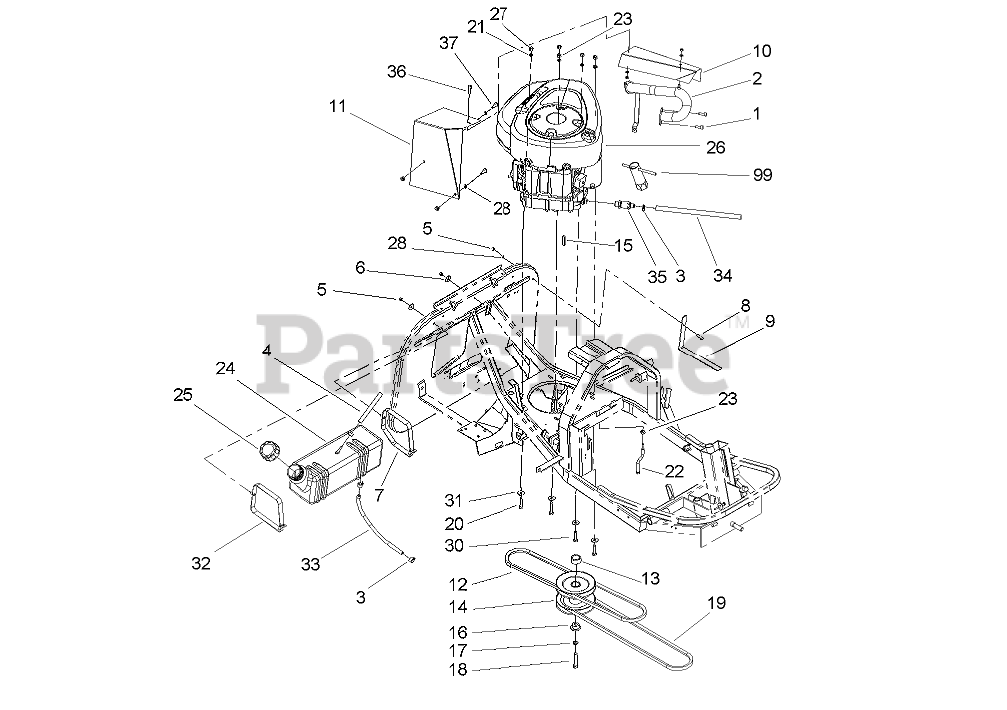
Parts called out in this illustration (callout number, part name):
1	SCREW-HSH
2	PIPE-EXHAUST
3	CLAMP-TUBE
4	Hose-Fuel
5	NUT-LOCK
6	Washer-Flat
7	STRAP-FUEL TANK, LEFT
8	SCREW-HH
9	Guard-Muffler
10	SHIELD-PIPE, EXHAUST
11	SHIELD-MUFFLER, REAR
12	BELT-TRANSMISSION
13	Spacer
14	PULLEY-ENGINE
15	KEY-SQUARE
16	Spacer
17	Washer-Lock
18	SCREW-HH
19	BELT-DECK
20	SCREW-HH
21	WASHER-PLAIN
22	Guide-Belt
23	NUT-HEX
24	TANK-FUEL
25	GAS CAP ASM
27	NUT-LOCK
28	WASHER-FLAT
30	Screw-HH
31	Washer-Flat
32	STRAP-FUEL TANK, RIGHT
33	Hose-Fuel
34	TUBE-DRAIN, OIL
35	VALVE-DRAIN, OIL
36	SCREW-HHF
37	SCREW-HHF
99	PLUG-WRENCH
